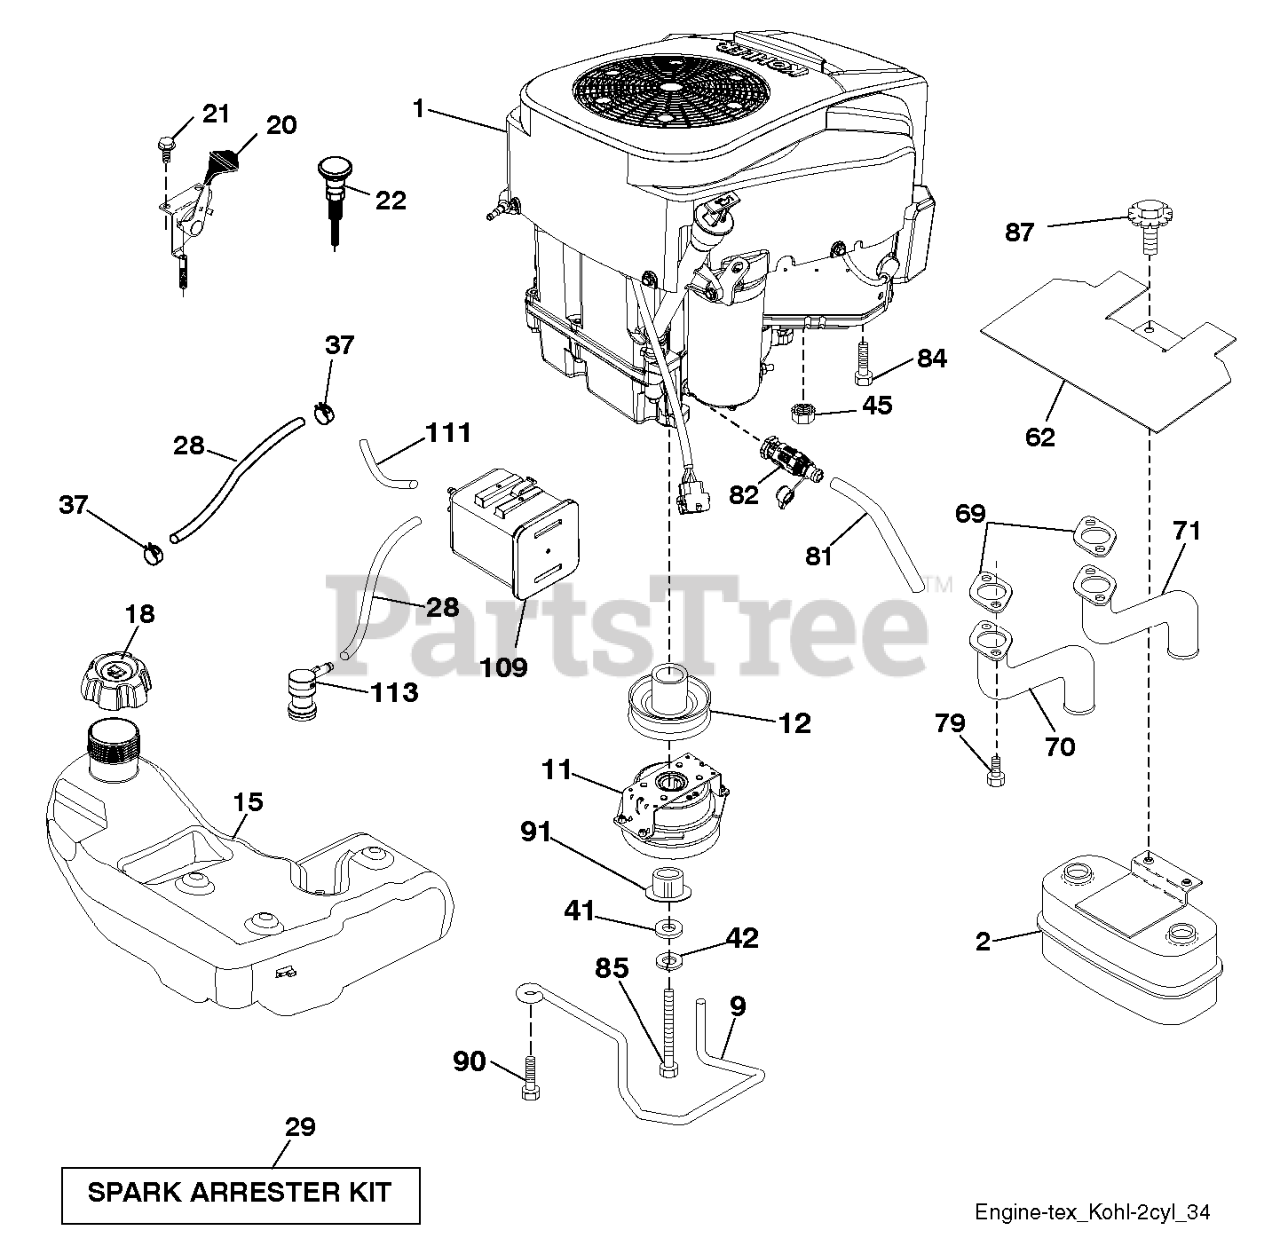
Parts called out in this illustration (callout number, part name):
2	MUFFLER.ASM.TWN.EXTNDED.DFLCTR
9	KEEPER.BELT.ENGINE.4.2
11	CLUTCH.ELECTRIC.LT.48"*
12	PULLEY.ENGINE.TUFFTORQ
15	TANK.ASM.FUEL.3GA.CARB
18	CAP.ASM.FL.RITCH.3"E10.SYM.498
20	THROTTLE CONTROL
21	SCREW.#10 X 0.750.BOS
22	CONTROL.CHOKE.ERGO.PUSH-IN.BLA
28	LINE.FUEL.64"REAR.EMIS
29	KIT.SPARK ARRESTOR 794945 B&S
37	HOSE CLAMP
42	LOCKWASHER
45	NUT
62	SHIELD.HEAT.MUFFLER
69	GASKET.EXHAUST.KOHL.CV18-CV26
70	RP.PIPE-EXHAUST LH
71	RP.PIPE-EXHAUST RH
79	SCREW.SOCKET HD.5/16-1
81	TUBE, DRAIN OIL ASM.
82	VALUE.OIL.DRAIN
84	SCREW 3/8-16X1
85	BOLT HEX 7/16-20X4-1/4"
87	BOLT.5/16-18UNCX3/4 W/SEMS.BLK
90	SCREW 3/8-16X1
91	PARTNER DECAL,
109	CANNISTER, CARBON
111	PURGE.LINE.36"REAR.CALIFORNIA
113	VALVE.SLANT.CARTRDG.90 DEG.TEX
